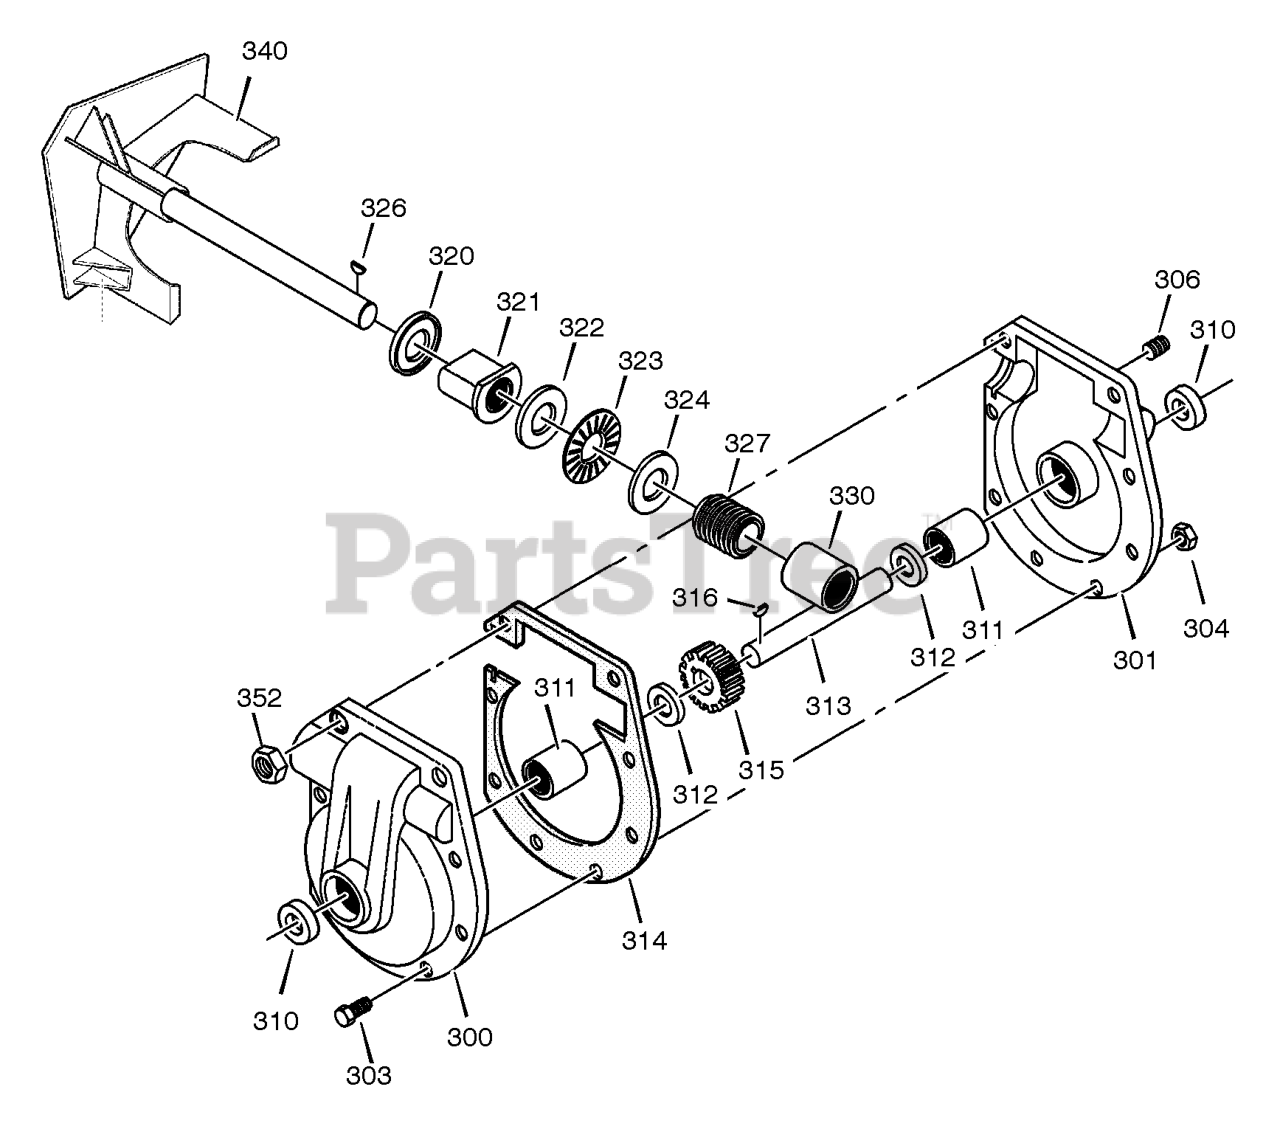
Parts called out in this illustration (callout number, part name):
300	CASE, GEAR, RH
301	CASE, GEAR, LH
303	SCREW,1/4-20X.75
304	NUT,1/4-20
305	NUT, 1/4-20 HEXKEPS
306	SCREW, 3/8-16 x 0.50
310	SEAL, OIL
311	BEARING, FL
312	WASHER, FLAT
313	SHAFT, AUGER OUTPUT
314	GASKET, GEAR BOX
315	WORM GEAR
316	KEY, WOODRUFF #61
320	BRNG, FL
321	SHAFT, AUGER INPUT
322	COLLAR, THRUST
323	PIN, SPRING
324	WASHER, FLAT
326	BRNG, FL
327	SEAL, OIL
330	BEARING
340	IMPELLER
